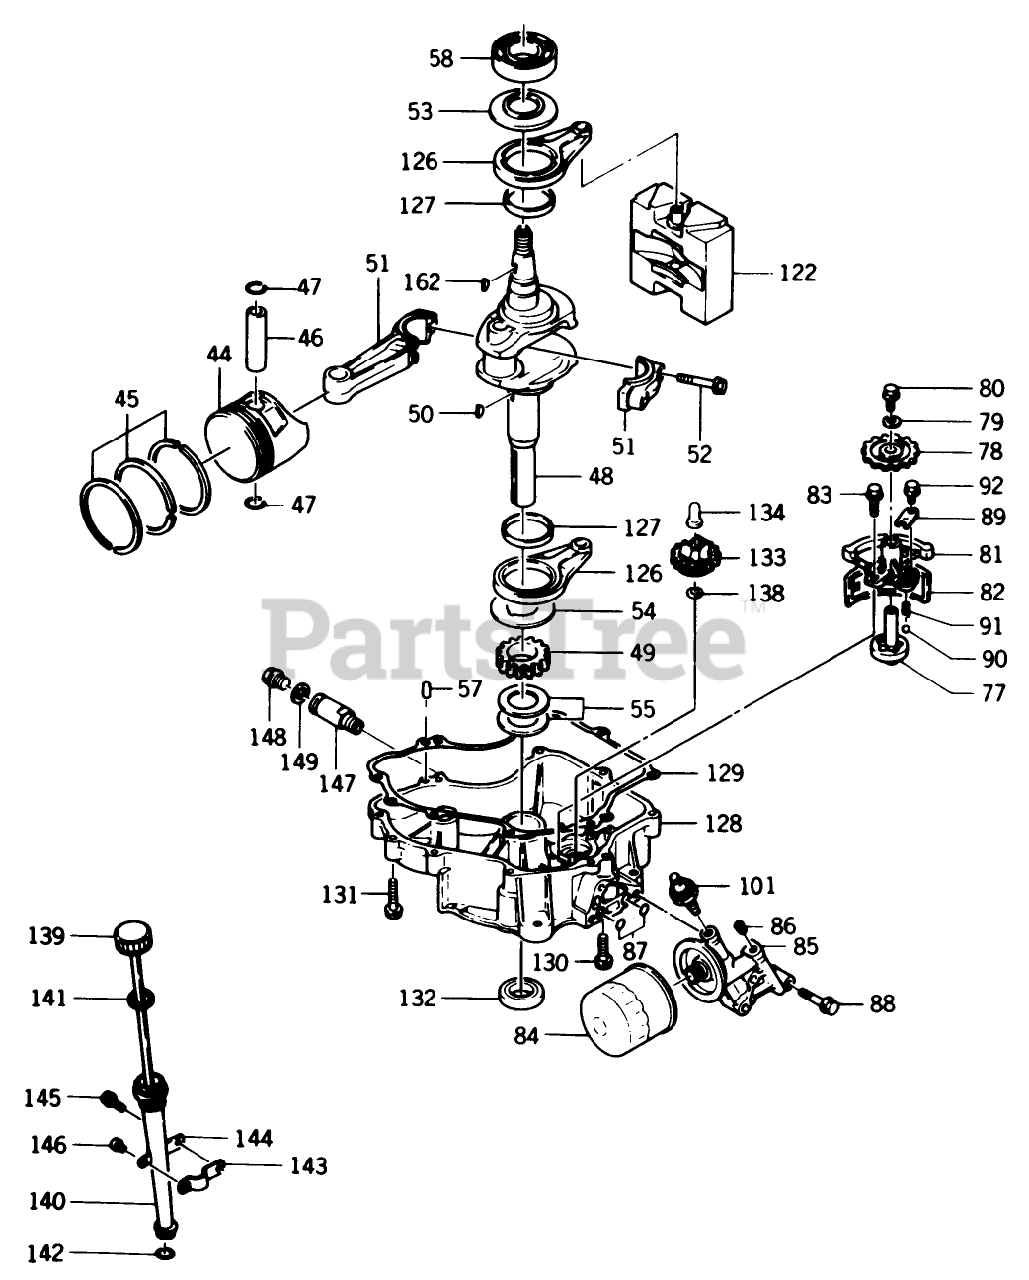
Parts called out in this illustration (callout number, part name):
50	KEY-WOODRUFF
88	BOLT (8 X 40)
92	BOLT-FLANGED
101	SWITCH-OIL PRESSURE
133	GOVERNON
134	SLEEVE-GOVERNOR
141	GASKET
142	O-RING
148	PLUG DRAIN
149	GASKET
162	KEY-WOODRUFF
